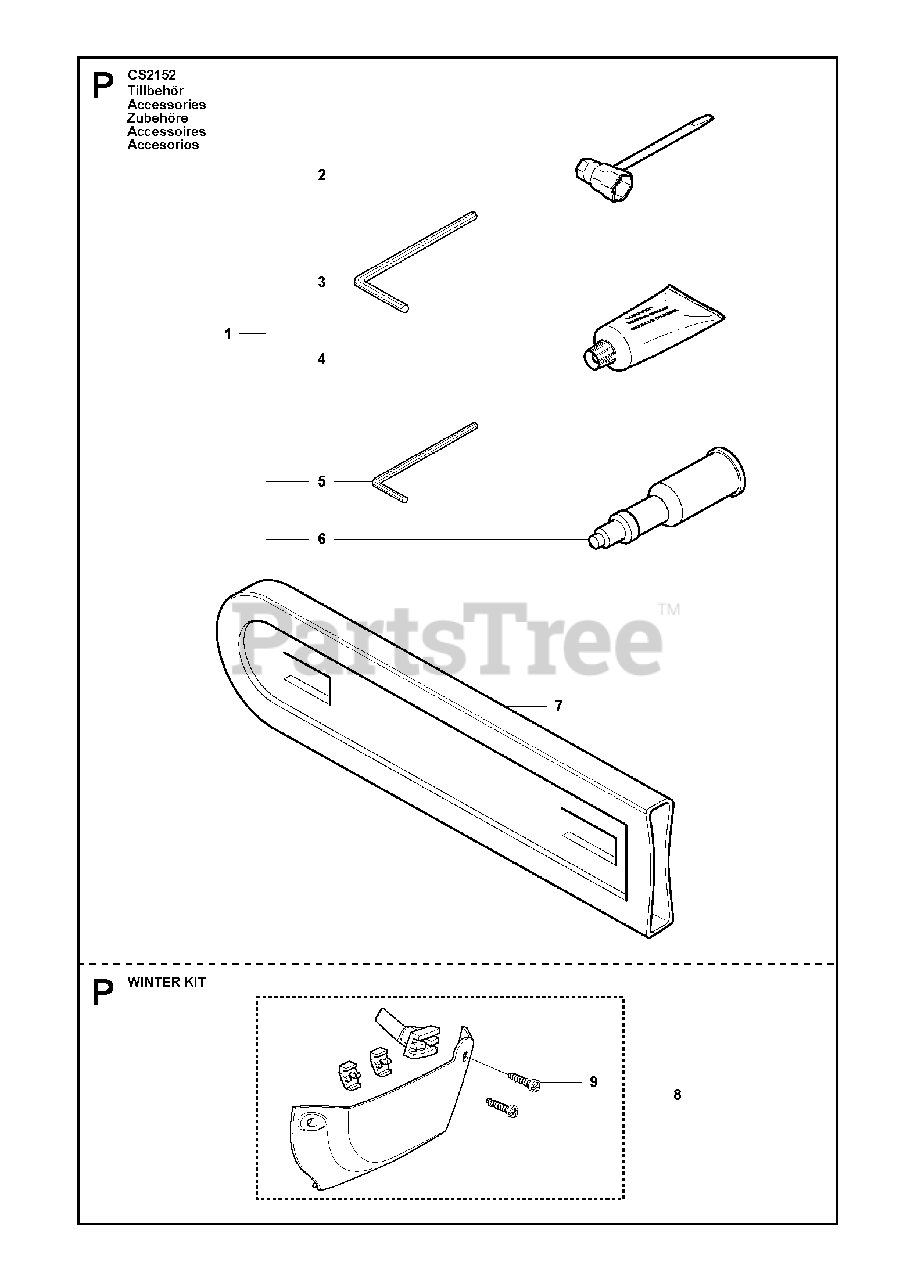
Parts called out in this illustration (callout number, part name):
1	TOOL KIT
2	COMBI TOOL
3	L-SPANNER
4	GREASE
5	L-SPANNER
6	GREASE GUN
7	BAR COVER
8	PROTECTOR
9	SCREW
